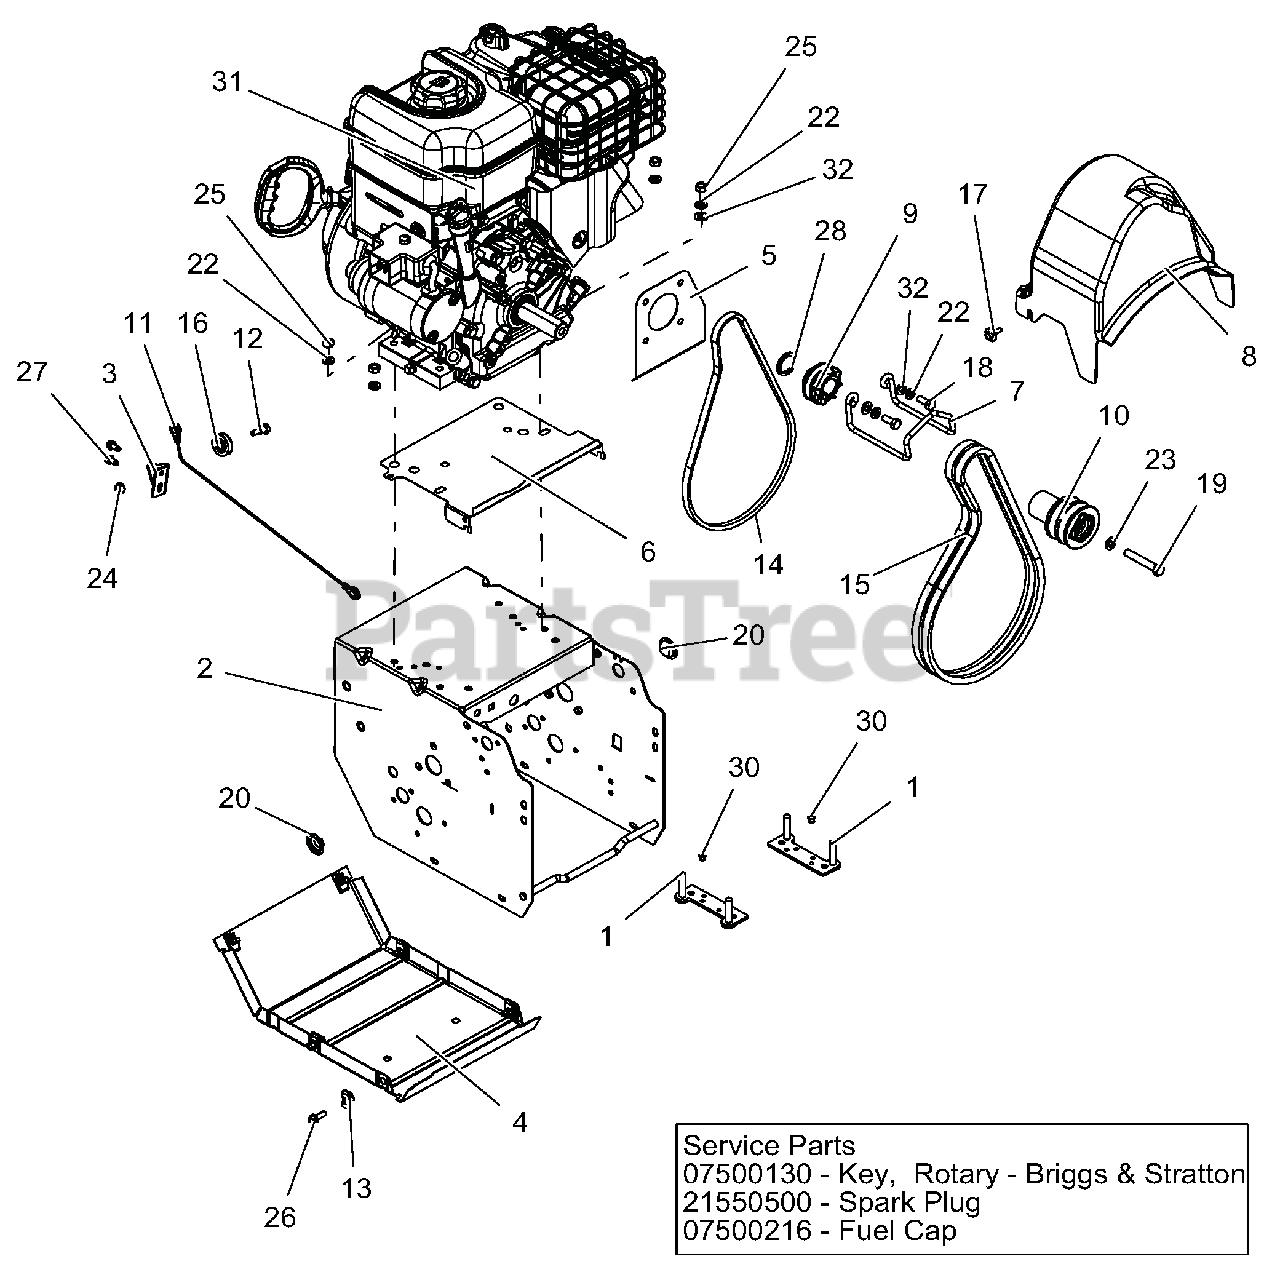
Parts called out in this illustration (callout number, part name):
1	STRAP, ENGINE BOLT-LARGE BRIGG
2	FRAME, 920/921
3	BRACKET, CABLE PULLEY
4	COVER, BOTTOM
5	BAFFLE, PRIMARY WATER
6	BAFFLE, BRIGGS MDL 20/21 WATER
7	FINGER, BELT
8	BELT COVER
9	SHEAVE, DRIVE
10	SHEAVE,ATTACHMENT 2-GRV
11	CABLE, LOWER TRACTION (DELUXE)
12	BOLT, SHLDR-.375X.375X.25-20
13	NUT-RTNR .25-20X.56
14	V-BELT, 3L-WRAPPED
15	V-BELT, HA-RAW EDGE (SET)
16	PULLEY, CABLE
17	SCR-TAP .25-20X.5 CAPTIVE
18	BLT-HEX .31-24X.75 YWZC GR5
19	BLT-HEX .38-24X2.25 YWZC GR5
20	PLUG, HOLE - .875" NYLON
22	WSHR-LK .312X.097 HVY YWZC
23	@WSHR-LK .38X.094 REG YWZC
24	@NUT-LK-CTR-FLG .25-20 YWZC
25	@NUT-HEX .31-18 YWZC
26	BLT-HEX .25-20X.75 HWH YZ GR5
27	SCR-TAP .25-20X.50 HWH TR YWZ
28	WSHR-FL-NYL 1.03 X 1.31 X .134
30	RVT-POP .187 YZ
31	ENGINE, BRIGGS SNOW 1450, 240V
32	@WSHR-FL-STL.344X.688X.065YWZC
